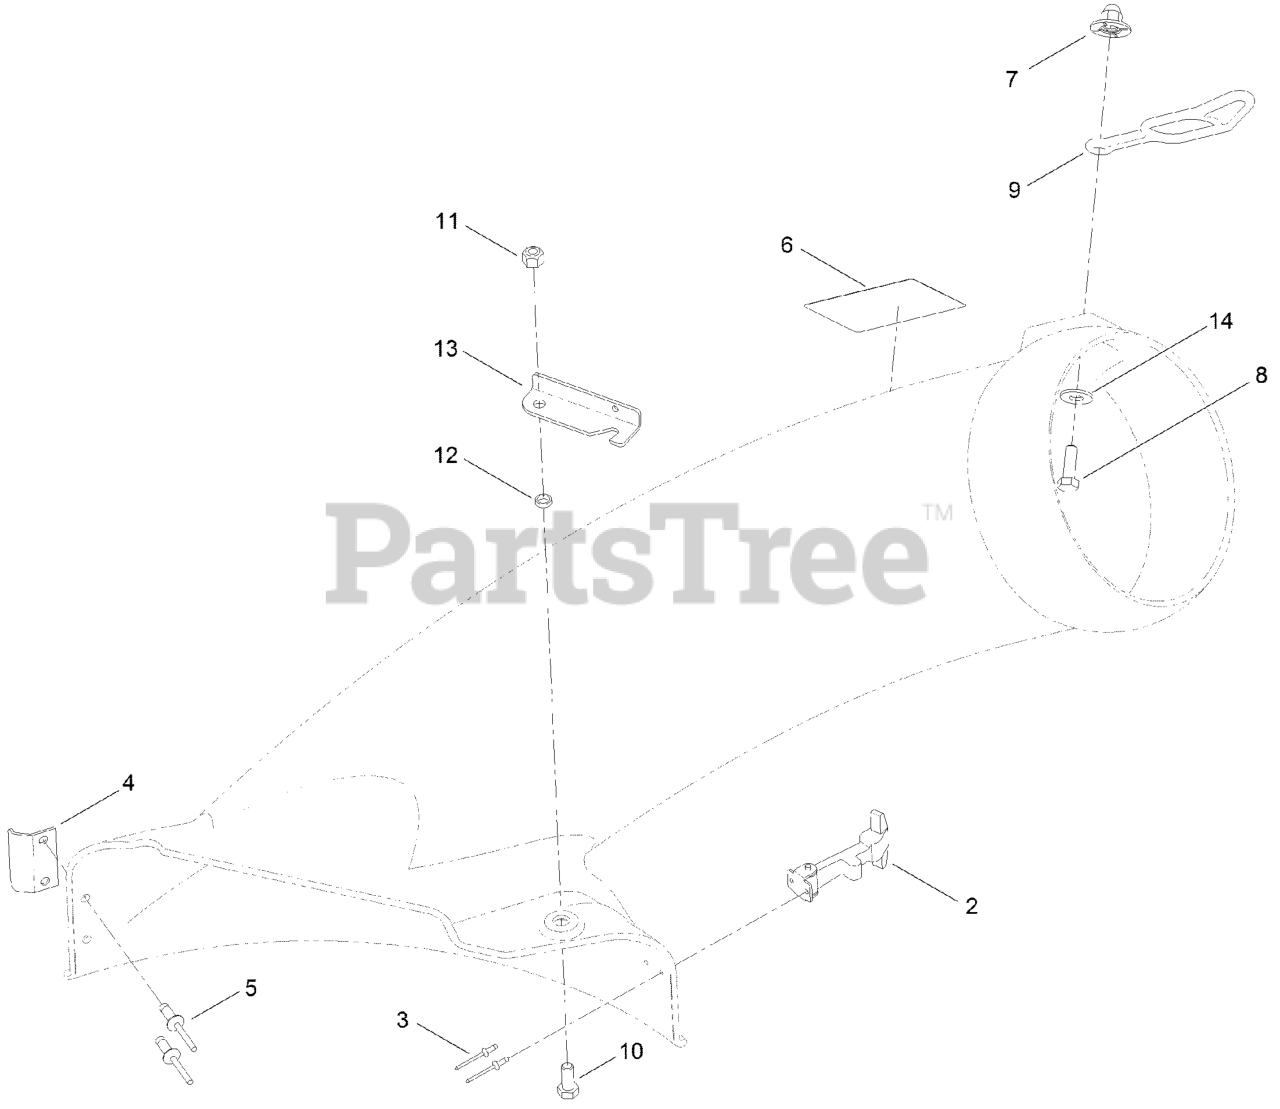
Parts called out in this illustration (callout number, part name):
2	HANDLE ASM
3	RIVET-POP
4	BRACKET-ELBOW
5	RIVET-BLIND
6	DECAL-DANGER
7	NUT-IMPELLER
8	SCREW-HH
9	RETAINER-DUCT
10	SCREW-HH
11	NUT-LOCK, NI
12	BUSHING
14	WASHER-FLAT
